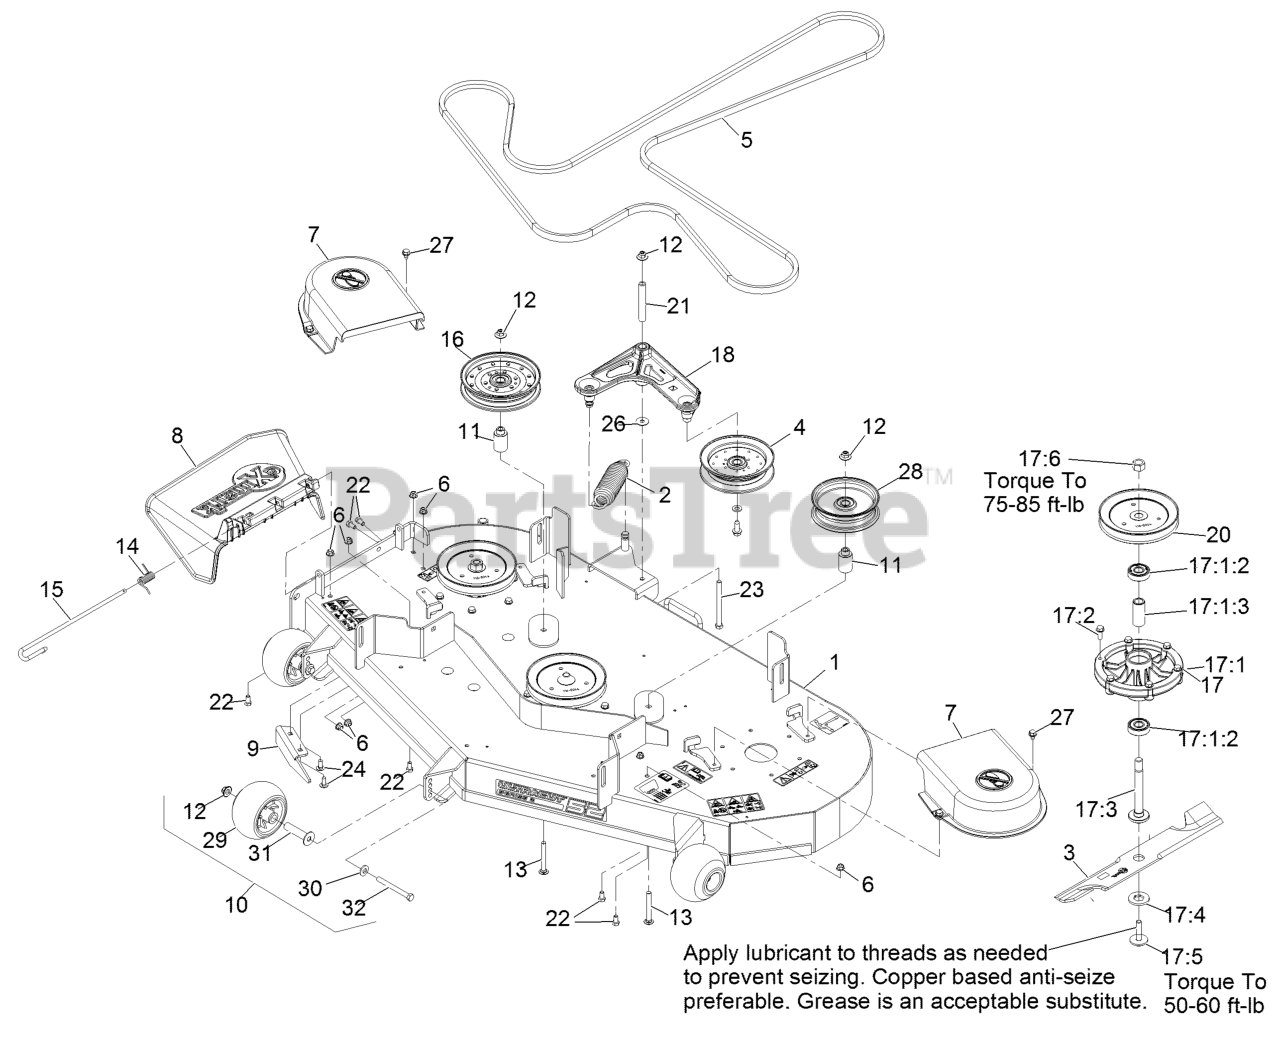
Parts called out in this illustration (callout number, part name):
1	ASM-522 DECK W/DECALS
2	SPRING-EXTENSION
5	BELT-B162.50
6	NUT-HF, NI
7	SHIELD-BELT
8	CHUTE DEFLECTOR XRK M056
9	BAFFLE-DISCHARGE
10	KIT, ANTI-SCALP ROLLER
11	BUSHING-IDLER
12	Nut-Nyloc 3/8-16 Flg
13	BOLT-CARRIAGE
14	SPRING-TORSION
15	PIN-CHUTE
17	CUTTER HOUSING ASM
17:1	HOUSING-CUTTER
17:1:2	BEARING
17:1:3	SPACER-BEARING
17:2	SCREW-TAPTITE
17:3	SPINDLE-HEX PILOT
17:4	WASHER-BLADE DRIVE
17:5	BOLT-BLADE, SEM
17:6	NUT-HEX
18	IDLER ARM ASM
20	SHEAVE,BLADE DRIVE 6.50
21	BUSHING
22	SCREW-HH
23	SCREW-HH
24	SCREW-CARR
28	IDLER-PULLEY, FLAT
29	ROLLER-SCALP, ANTI
30	WASHER-BELLEVILLE
31	AXLE, ROLLER
32	SCREW-HH 3/8-16 X 3 3/4 GR 8
